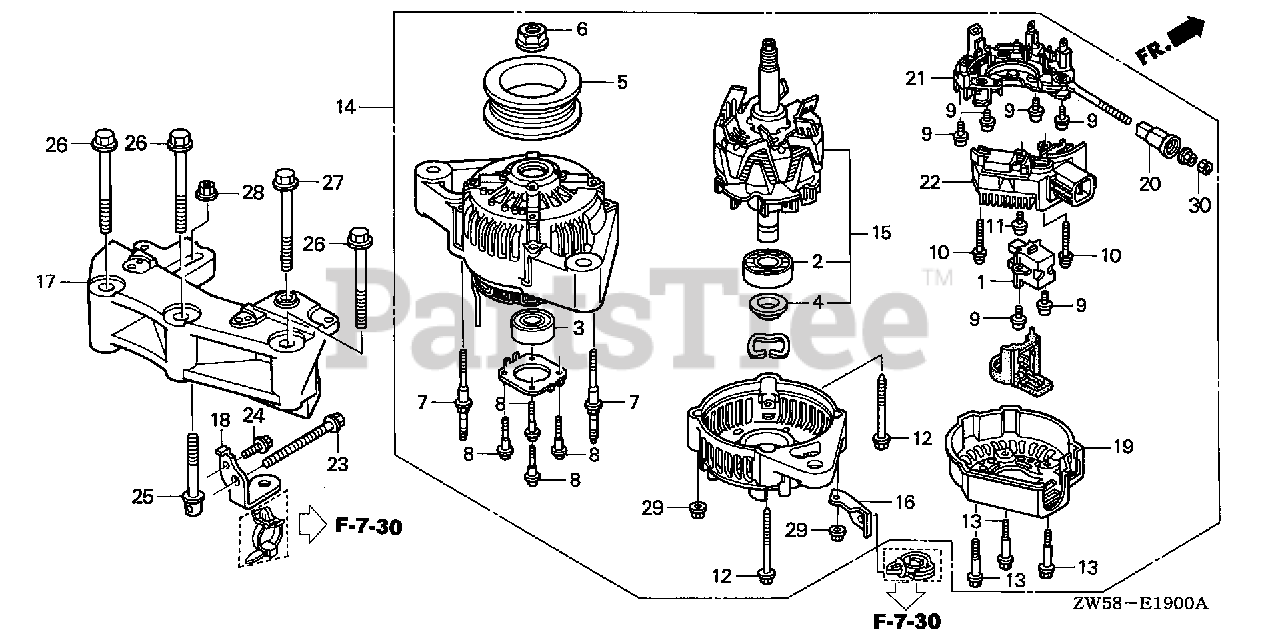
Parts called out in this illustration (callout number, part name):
1	HOLDER ASSY., BRUSH
2	BEARING, RR.
3	BEARING, FR.
4	COVER, BEARING
6	NUT, PULLEY LOCK
7	BOLT, STUD
9	SCREW-WASHER
10	SCREW-WASHER (4X25)
12	BOLT-WASHER
14	ALTERNATOR ASSY.
15	ROTOR ASSY.
16	BRACKET, HARNESS CLAMP
17	BRACKET, ALTERNATOR
18	STAY, ALTERNATOR
19	END COVER, RR.
20	BUSH, INSULATION
21	RECTIFIER ASSY.
22	REGULATOR ASSY.
23	BOLT, SPECIAL ADJUSTER
24	BOLT, FLANGE (6X14)
25	BOLT, TENSIONER
26	BOLT, FLANGE (10X70)
27	BOLT, FLANGE (10X80)
28	NUT, FLANGE (8MM)
29	NUT-WASHER (5MM)
30	NUT, HEX. (6MM)
